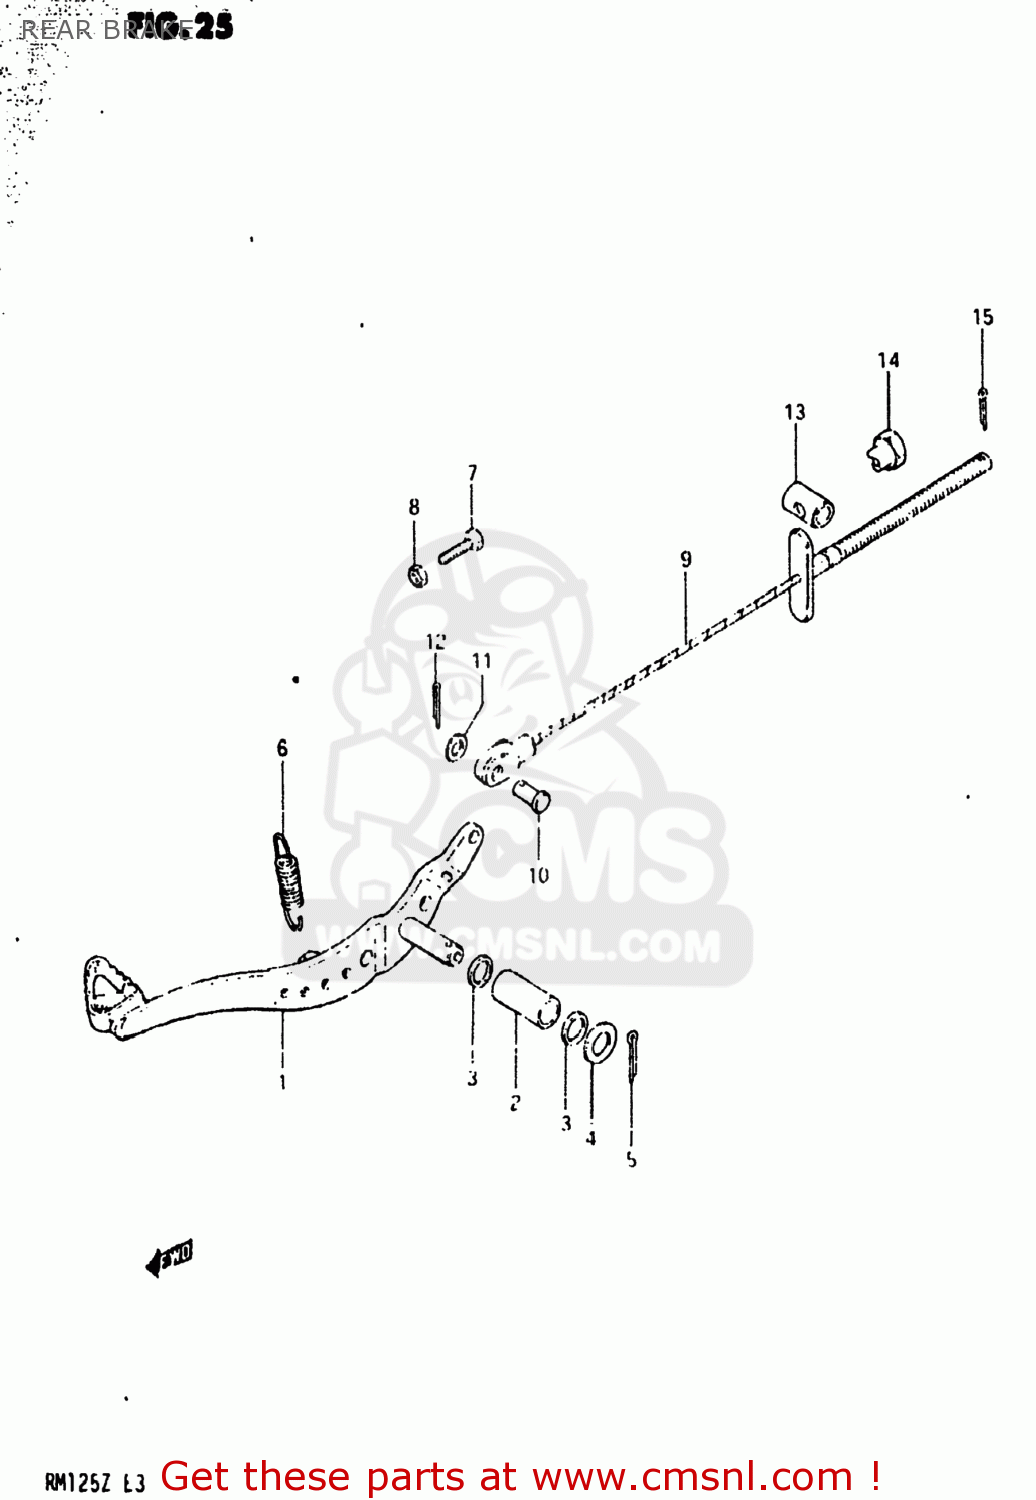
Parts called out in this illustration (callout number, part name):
1	PEDAL,BRAKE
2	BUSHING
3	O RING(D:2.2,ID:11.8)
4	WASHER
5	PIN 30X20
6	SPRING
7	BOLT(6X23)
8	NUT
9	CABLE ASSEMBLY,REAR BRAKE
10	PIN(L:17.5)
11	WASHER
12	PIN 20X20
13	PIN
14	NUT
15	PIN
